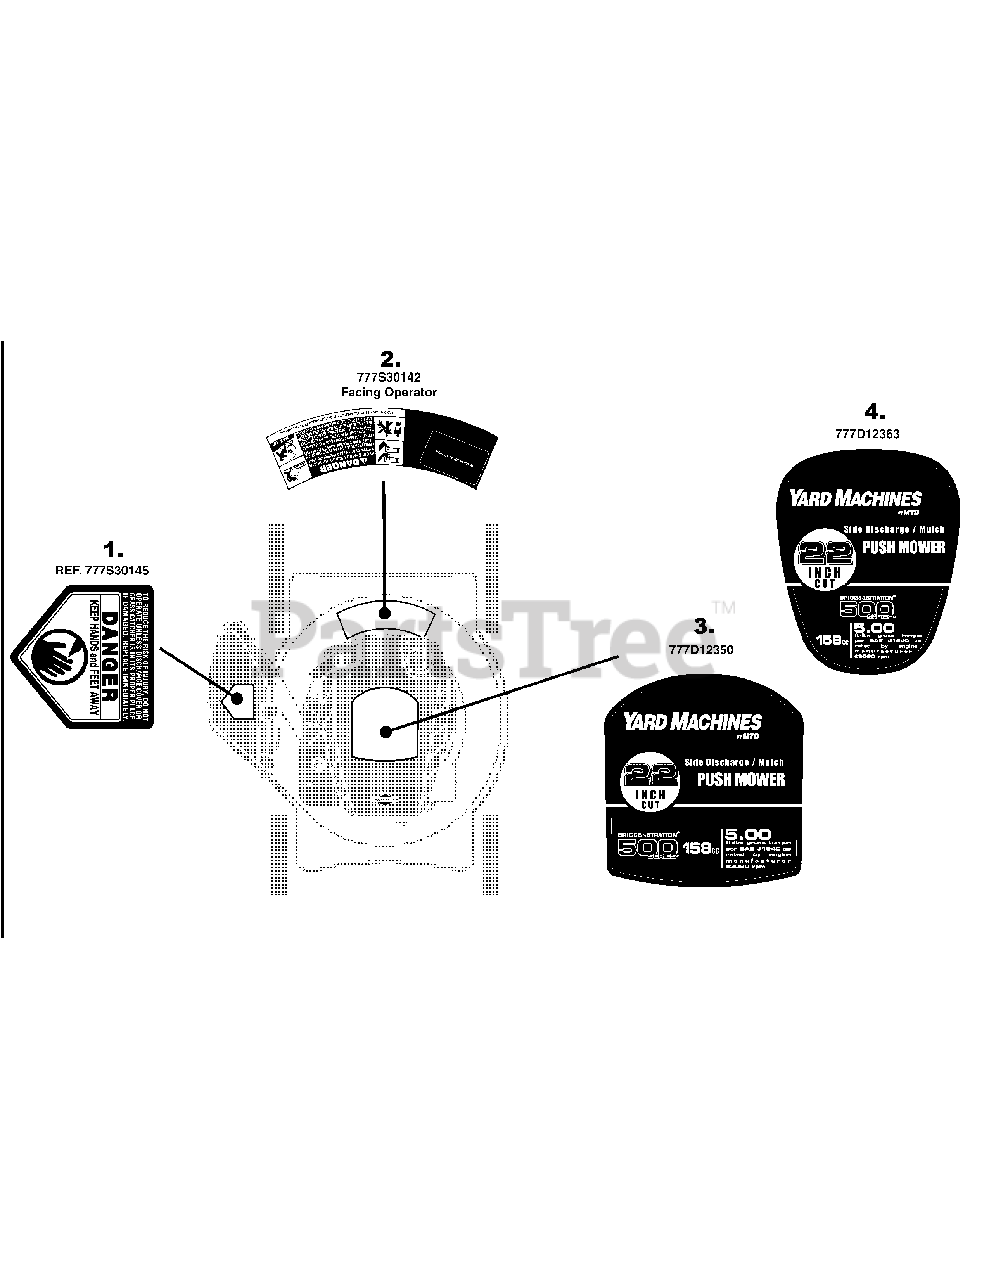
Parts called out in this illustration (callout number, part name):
1	LABEL
2	LABEL-DANGER CURVE
3	LABEL-MOWER SHROUD YARD MACH 22"
4	LABEL-MOWER SHROUD YARD MACH 22"
